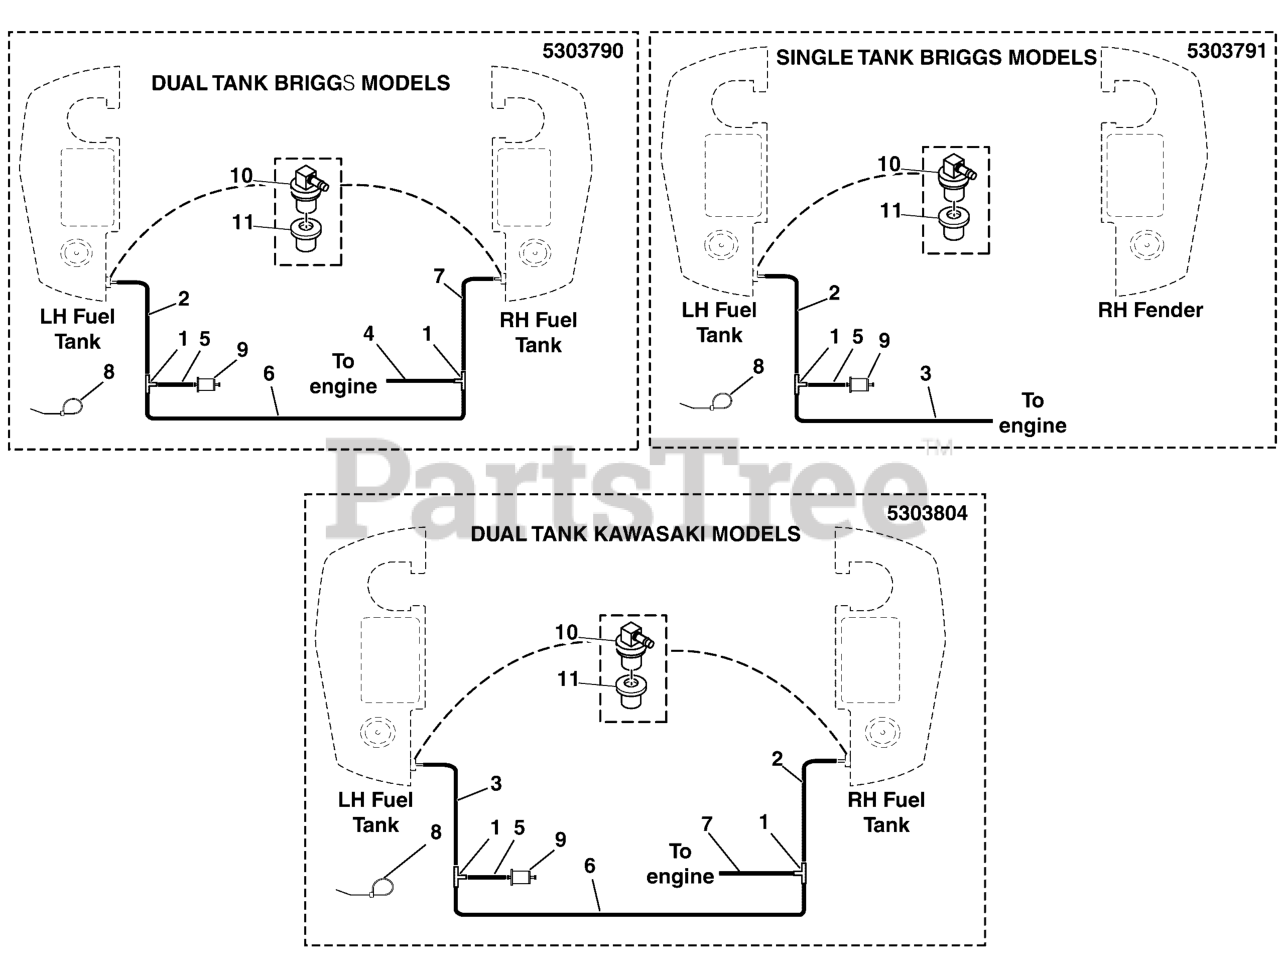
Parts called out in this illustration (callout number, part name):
1	FITTING, 3/16" TEE, BARB TYPE, HDPE
2	HOSE, VAPOR, 5MM ID, 26.00 LG
3	HOSE, VAPOR, 5MM ID, 12.00 LG
4	HOSE, VAPOR, 5MM ID, 5.00 LG
5	HOSE, VAPOR, 5MM ID, 2.00 LG
6	HOSE, VAPOR, 5MM ID, 10.50 LG
7	HOSE, VAPOR, 5MM ID, 18.00 LG
8	TIE,SELF-LOCKING, 6"
9	FILTER, FUEL
10	REMOTE VENT ASSEMBLY
11	GROMMET
